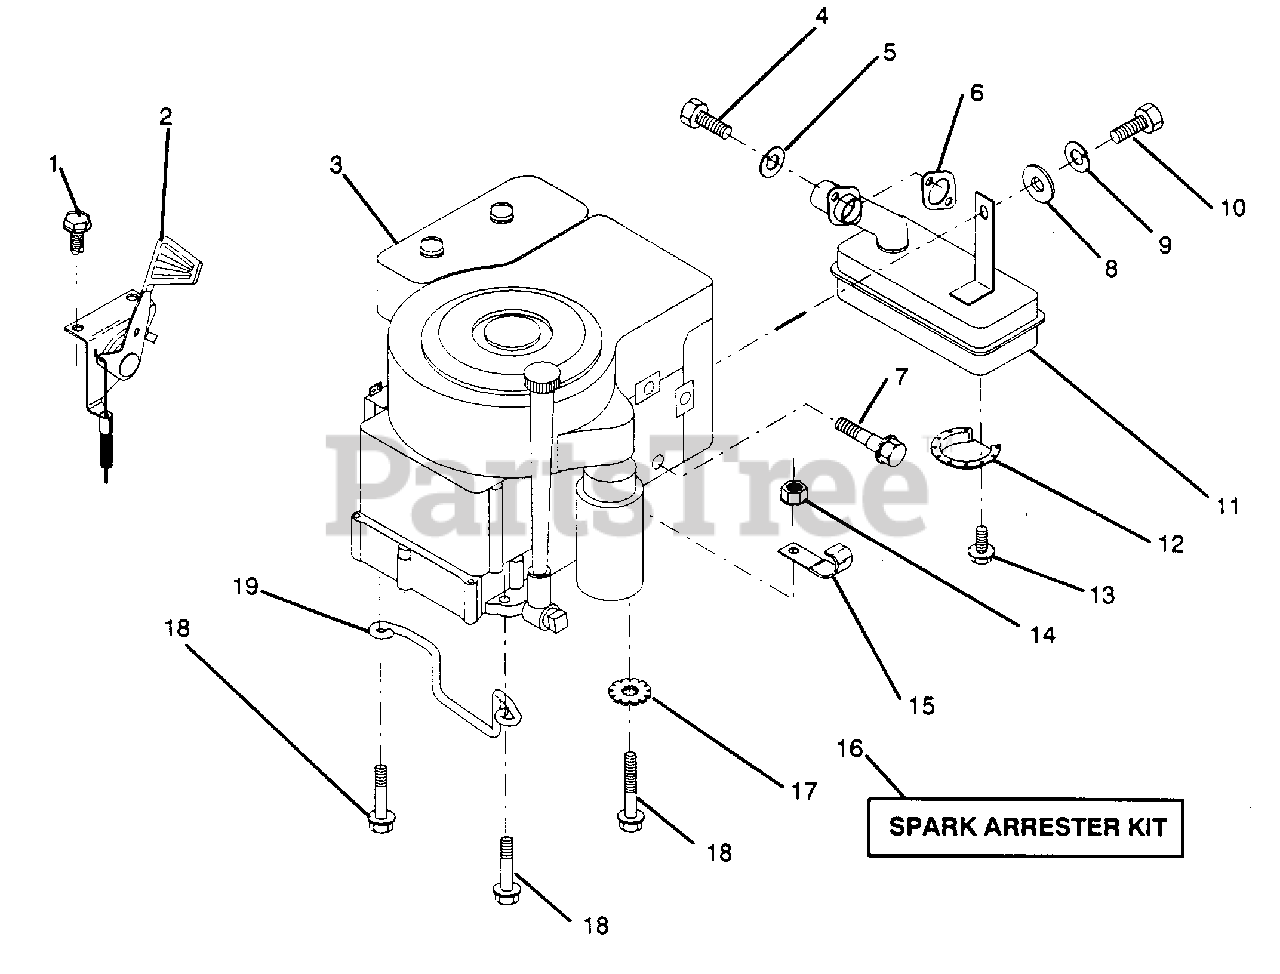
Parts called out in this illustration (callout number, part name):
1	Screw, Hex Thd. Cut 1/4-20 x 1/2 (AYP part number)
2	Control, Throttle (AYP part number)
3	Engine, Briggs and Stratton
4	Screw, Hex Hd. Cap 5/16-18 x 3/4 (AYP part number)
5	Washer, Lock Heavy Helical Spring 5/16 (AYP part number)
6	Gasket, Exhaust (AYP part number)
7	Bolt, Shoulder 5/16 (AYP part number)
8	Washer, 5/16 x 3/4 x 16 Ga. (AYP part number)
9	Washer, Lock Heavy Helical Spring 1/4 (AYP part number)
10	Bolt, Hex Fin. 1/4-20 UNC x 1-1/4 (AYP part number)
11	Muffler (AYP part number)
12	Deflector, Muffler (AYP part number)
13	Screw, Spiderlock Hex Hd. 8 x 1/2 ABTPS (AYP part number)
14	Nut, Keps 3/8-16 (AYP part number)
15	Clip, Fuel Line (AYP part number)
16	Arrestor, Spark (optional equipment) (AYP part number)
17	Washer lock, Ext. Tooth 3/8 (AYP part number)
18	Screw, Hex Wsh Hd Thdrol 3/8-16 x 2 (AYP part number)
19	Keeper, Ground Drive Belt (AYP part number)
